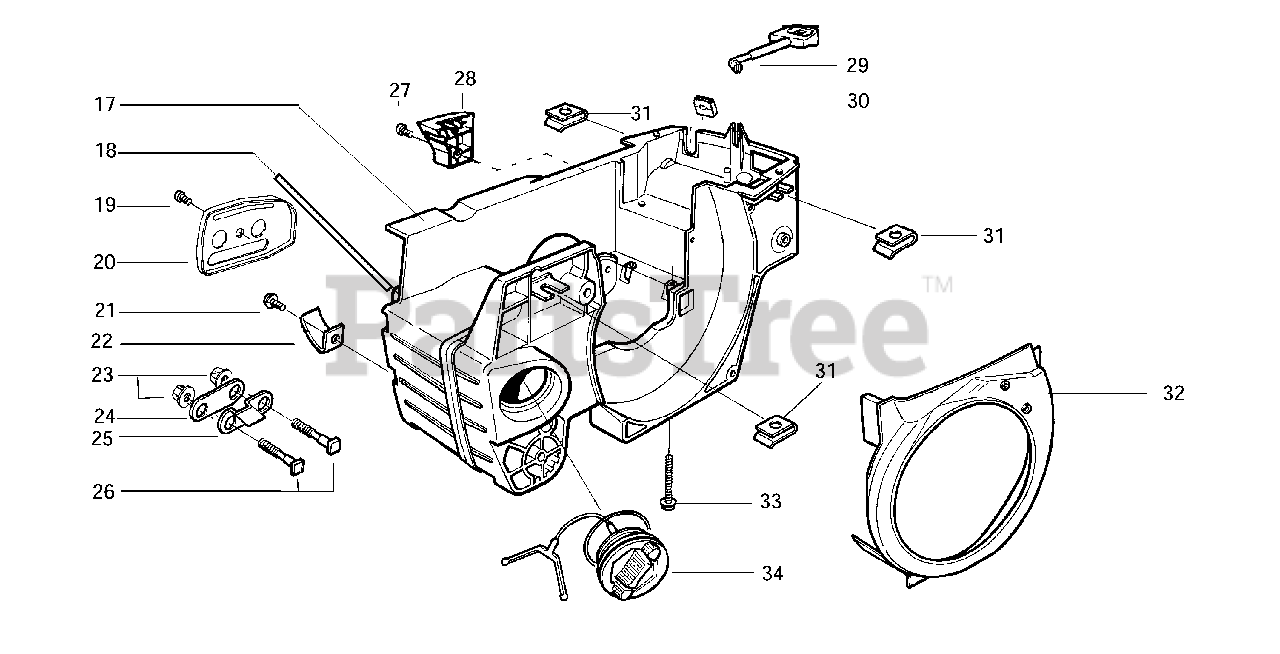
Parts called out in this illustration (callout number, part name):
17	Kit - Chassis Ass'y.
18	Tube-Oil Vent
19	Screw
22	Chain Catcher
25	Bar Stud Plate
29	Choke Lever
31	Type 'U' Speed Nut
32	Baffle Plate
34	Assy.- Oil Tank Cap
